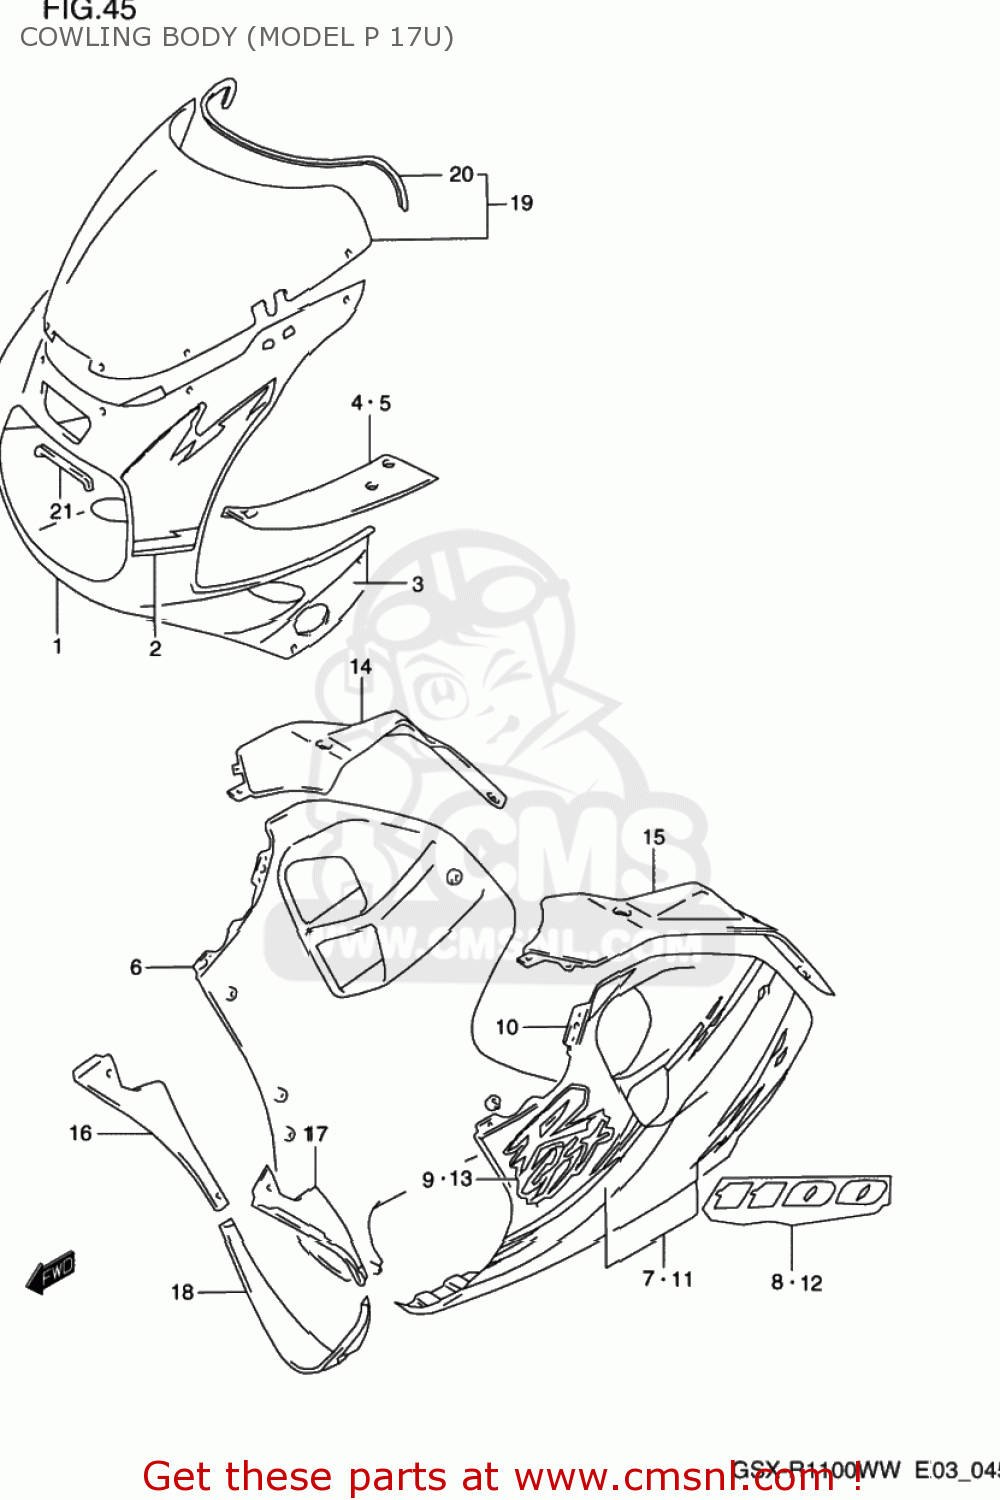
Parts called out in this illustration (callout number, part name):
1	COWLING ASSY,BODY
2	TAPE SET,COWL BODY FR
3	TAPE SET,COWL BODY SIDE
4	PANEL,UPR,R
5	PANEL,UPR,L
6	COWLING ASSY,UNDER,R
7	TAPE SET,COWL UNDER,R
8	EMBLEM,COWLING,UNDER
9	EMBLEM,COWLING UNDER
10	COWLING ASSEMBLY,UNDER,LEFT
11	TAPE SET,COWLING,UNDER
12	EMBLEM,COWLING,UNDER
13	EMBLEM,COWLING UNDER
14	PANEL,LWR,R
15	PANEL,LWR,L
16	COWLING,UNDER INNER,R
17	COWLING,UNDER INNER,L
18	COWLING,UNDER CTR
19	SCREEN SET,WIND
20	MOLDING,WINDSCREEN
21	CUSHION,FR POSITION LAMP
